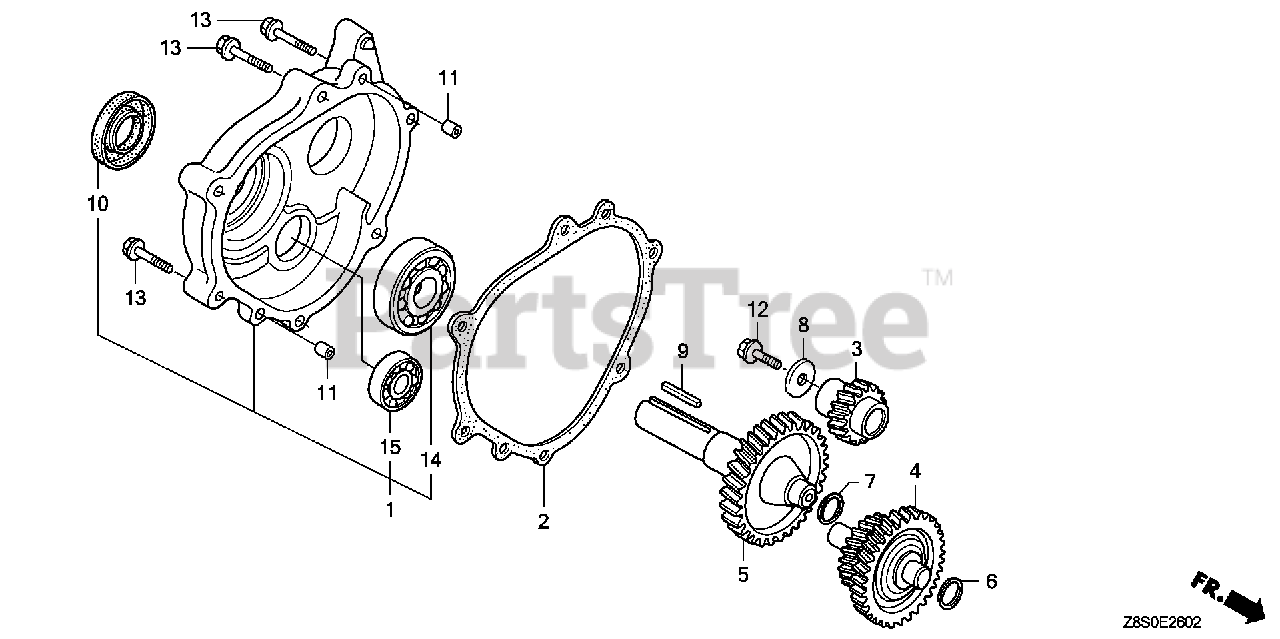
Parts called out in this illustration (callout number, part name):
1	COVER ASSY., REDUCTION CASE
2	GASKET, CHAIN CASE COVER
3	GEAR, PRIMARY DRIVE (17T)
4	COUNTERSHAFT
5	SHAFT, P.T.O. (H-TYPE)
6	SHIM A
7	SHIM B
8	WASHER (8MM)
9	KEY (6.3X6.3X43)
10	OIL SEAL (30X46X8) (NOK ASIA)
11	PIN A, DOWEL (8X14)
12	BOLT, FLANGE (8X25)
13	BOLT, FLANGE (8X40) Use up to Engine SN 1003236.
14	BEARING, RADIAL BALL (6206)
15	BEARING, RADIAL BALL (6302)
